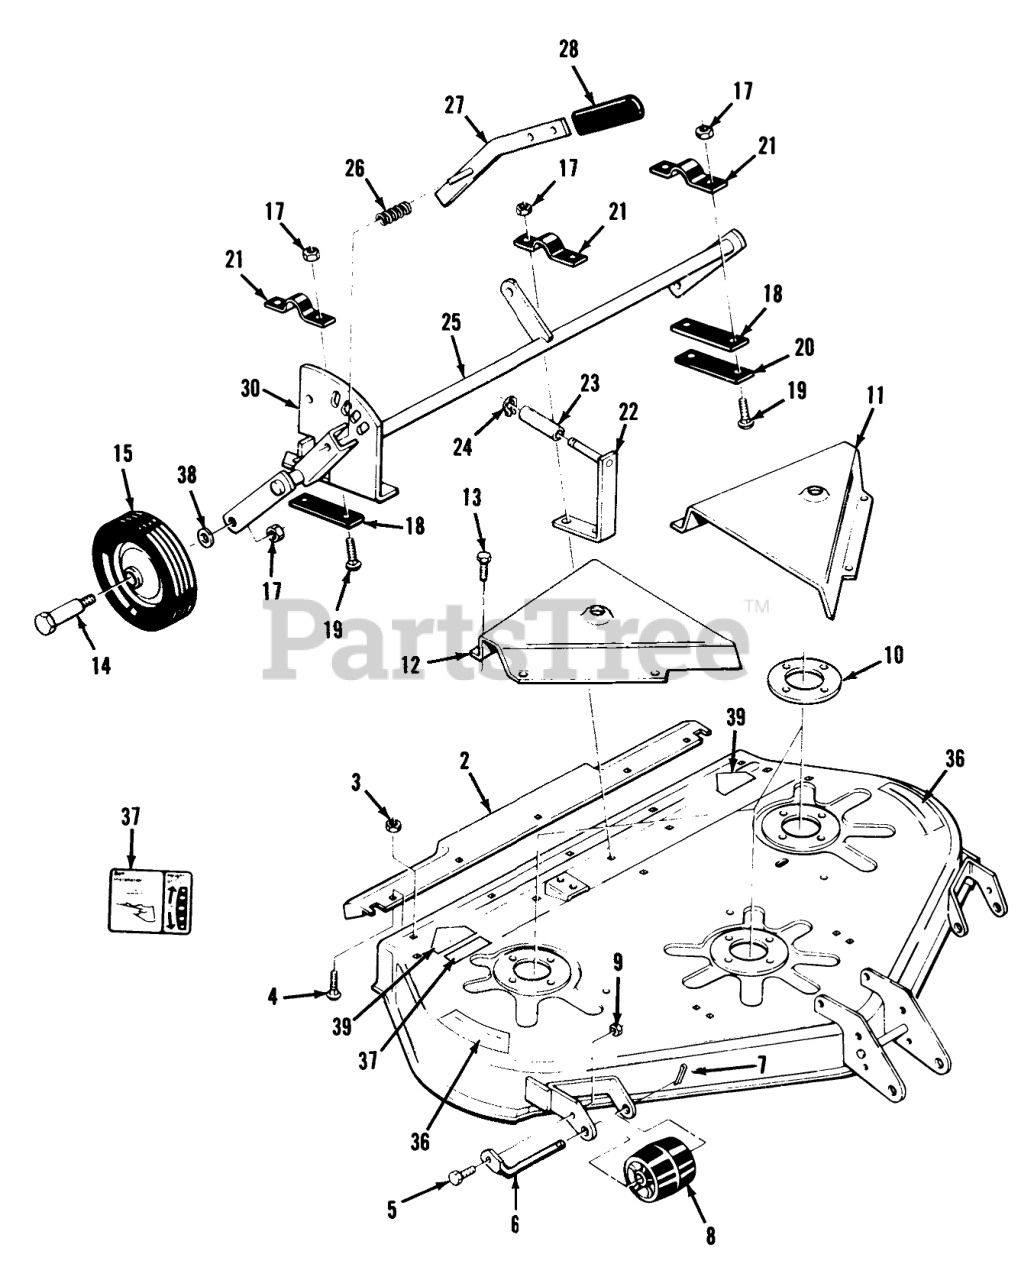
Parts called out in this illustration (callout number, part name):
1	ASSY 42" MOWER RE R
2	EXTENSION R
3	NUT-LOCK, NI
4	BOLT-CARR
5	SCREW-HH
6	ROLLER-SHAFT
8	ROLLER ASSY
9	NUT-LOCK, NI
10	PLATE-SPINDLE
11	Belt Cover LH
12	Belt Cover RH
13	Bolt
14	BOLT-SHOULDER
15	WHEEL ASM
17	NUT-LOCK, NI
18	STRAP 1/16 B
19	BOLT-CARR
20	Bar
22	Guide Bracket
23	SPACER
24	Snap Ring
25	WLDMT-GAGE WHEEL R
26	SPRING-COMPRESSION
27	Lever
30	QUADRANT R
36	DECAL - DANGER
37	DECAL-HEIGHT BELT
38	WASHER
39	DECAL-DANGER
